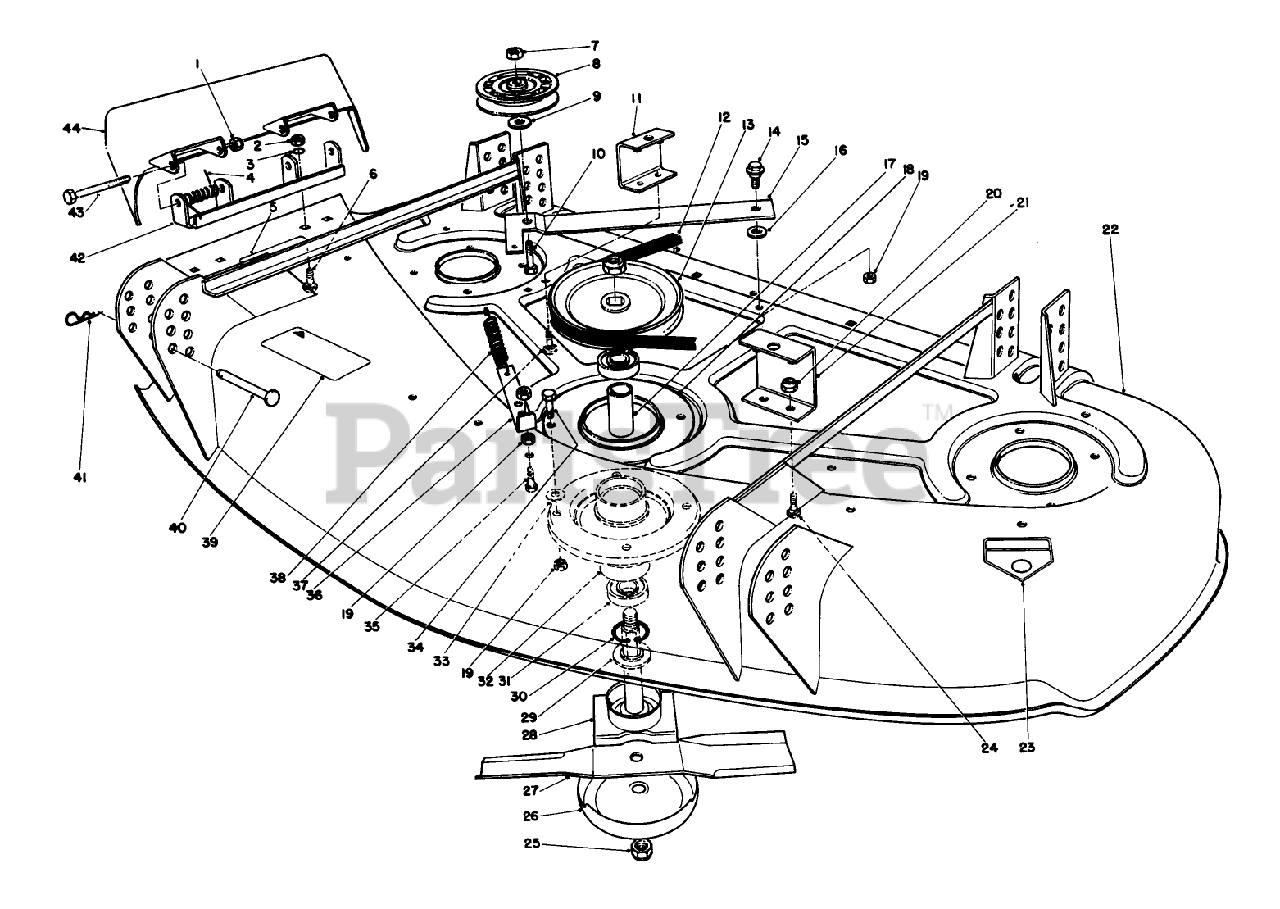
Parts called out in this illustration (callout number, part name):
1	NUT-HEX
2	NUT-HEX
3	WASHER-LOCK
4	SPRING
7	NUT-LOCK, CONE
9	WASHER-FLAT
10	SCREW-HH
12	V-BELT-DECK
14	SCREW-SHOULDER
16	WASHER
19	NUT-LOCK, CONE
20	NUT-LOCK, NI
23	DECAL-DANGER
24	SCREW-CARR
25	NUT-SPECIAL
28	SPINDLE SHAFT WA
29	SPACER-SPINDLE
31	BEARING-BALL
33	WASHER-FLAT
34	SCREW-HH
35	SCREW-HH
37	SCREW-CARR
38	SPRING-EXTENSION, DECK
40	PIN-CLEVIS
41	PIN-HAIR
42	PIVOT BRKT WA
43	SCREW-HH
